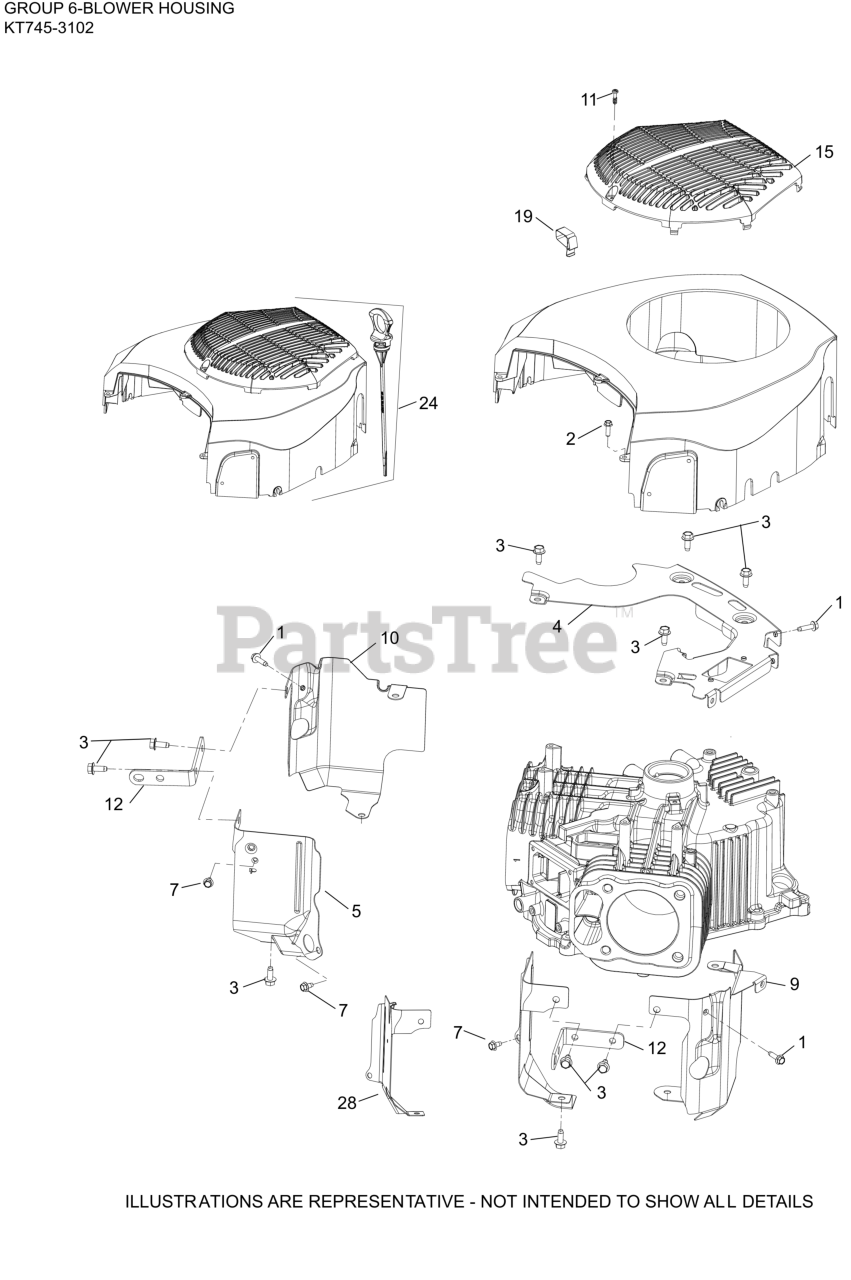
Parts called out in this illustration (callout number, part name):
1	SCREW, THD FRM-USE 25 086 473-S
2	SCREW, HI-LOW
3	SCREW, THREAD FORMING
4	PLATE, BACKING
5	BAFFLE, VALLEY #1
7	SCREW, THREAD FORMING
9	BAFFLE, LEFT BARREL
10	BAFFLE, RIGHT BARREL
11	SCREW, M5-2.42 (PT) THREAD
12	STRAP, LIFTING
15	GUARD, FIXED
19	CLIP, BLOWER HOUSING
24	KIT, BLOWER HOUSING
28	BAFFLE, VALLEY #2
